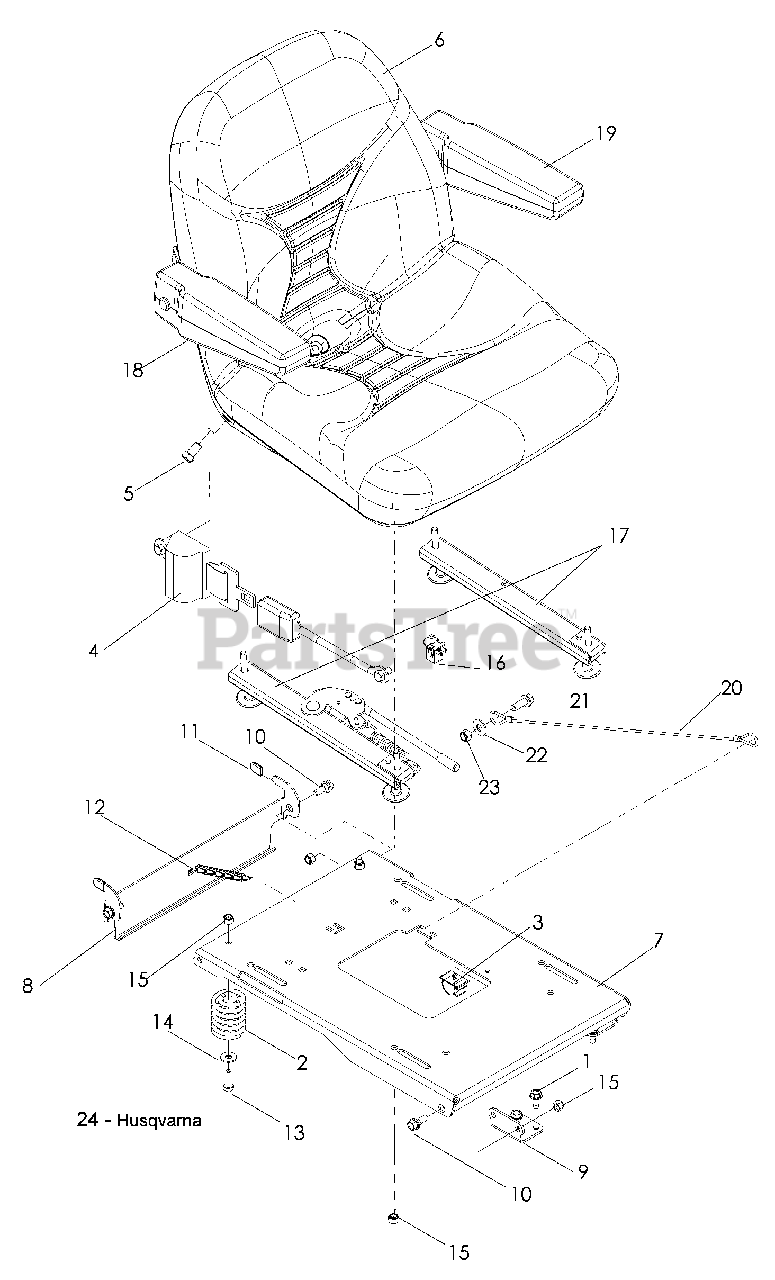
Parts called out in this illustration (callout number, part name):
1	BOLT 5/16-18 x ¾ THD FRM
2	SPRING, SEAT
3	CLIP, PUSH MOUNT
4	SEAT BELT, RETRACTABLE
5	HCS 7/16-20 x ¾
6	SEAT
8	LATCH, SEAT
9	PIVOT, SEAT PAN
10	BOLT 5/16-18 HEX HD
11	GRIP, VINYL
13	HCS 5/16-18 x 1
14	WASHER 5/16 STD FLT
15	NUT 5/16-18 HEX NYLOC
16	SWITCH, SEAT
17	SEAT RAIL SET COMPLETE
18	ARM REST ASSM, RT
19	ARM REST ASSM, LT
20	SEAT LANYARD
21	HCS, 3/8-16 x 1 WHIZLK
22	WASHER 3/8 STD FLT
23	NUT 3/8-16 HEX NYLOC
